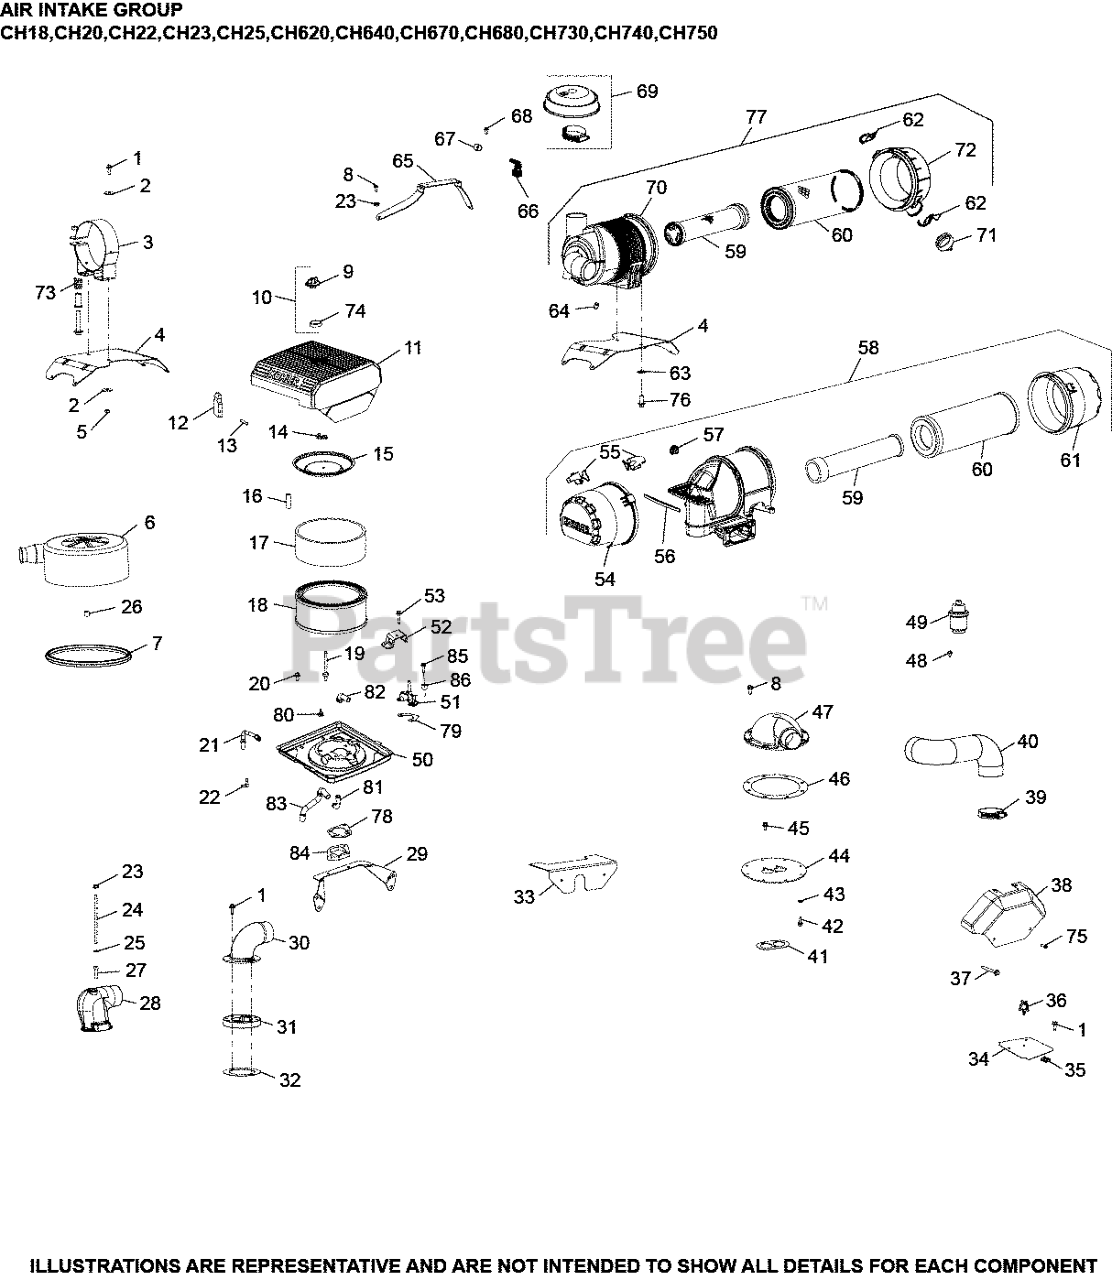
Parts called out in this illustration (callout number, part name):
9	KNOB, COVER
10	KIT, KNOB W/SEAL
11	COVER, AIR CLEANER
11	KIT, AIR CLEANER COVER
14	NUT, WING
15	COVER, INNER AIR CLEANER
16	SEAL, BREATHER
17	PRE-CLEANER (HIGH)
18	ELEMENT, AIR FILTER (HIGH) - Also available Retail Packaged 24 883 03-S1 Air Filter Kit
20	SCREW, FLG THD FRM M6X1.0X16
29	BRACKET, AIR CLEANER BASE
48	SCREW, THREAD FORMING
50	KIT, AIR CLEANER BASE
51	BRACKET, AIR CLEANER
78	GASKET, AIR CLEANER BASE
80	PLUG, HOLE
